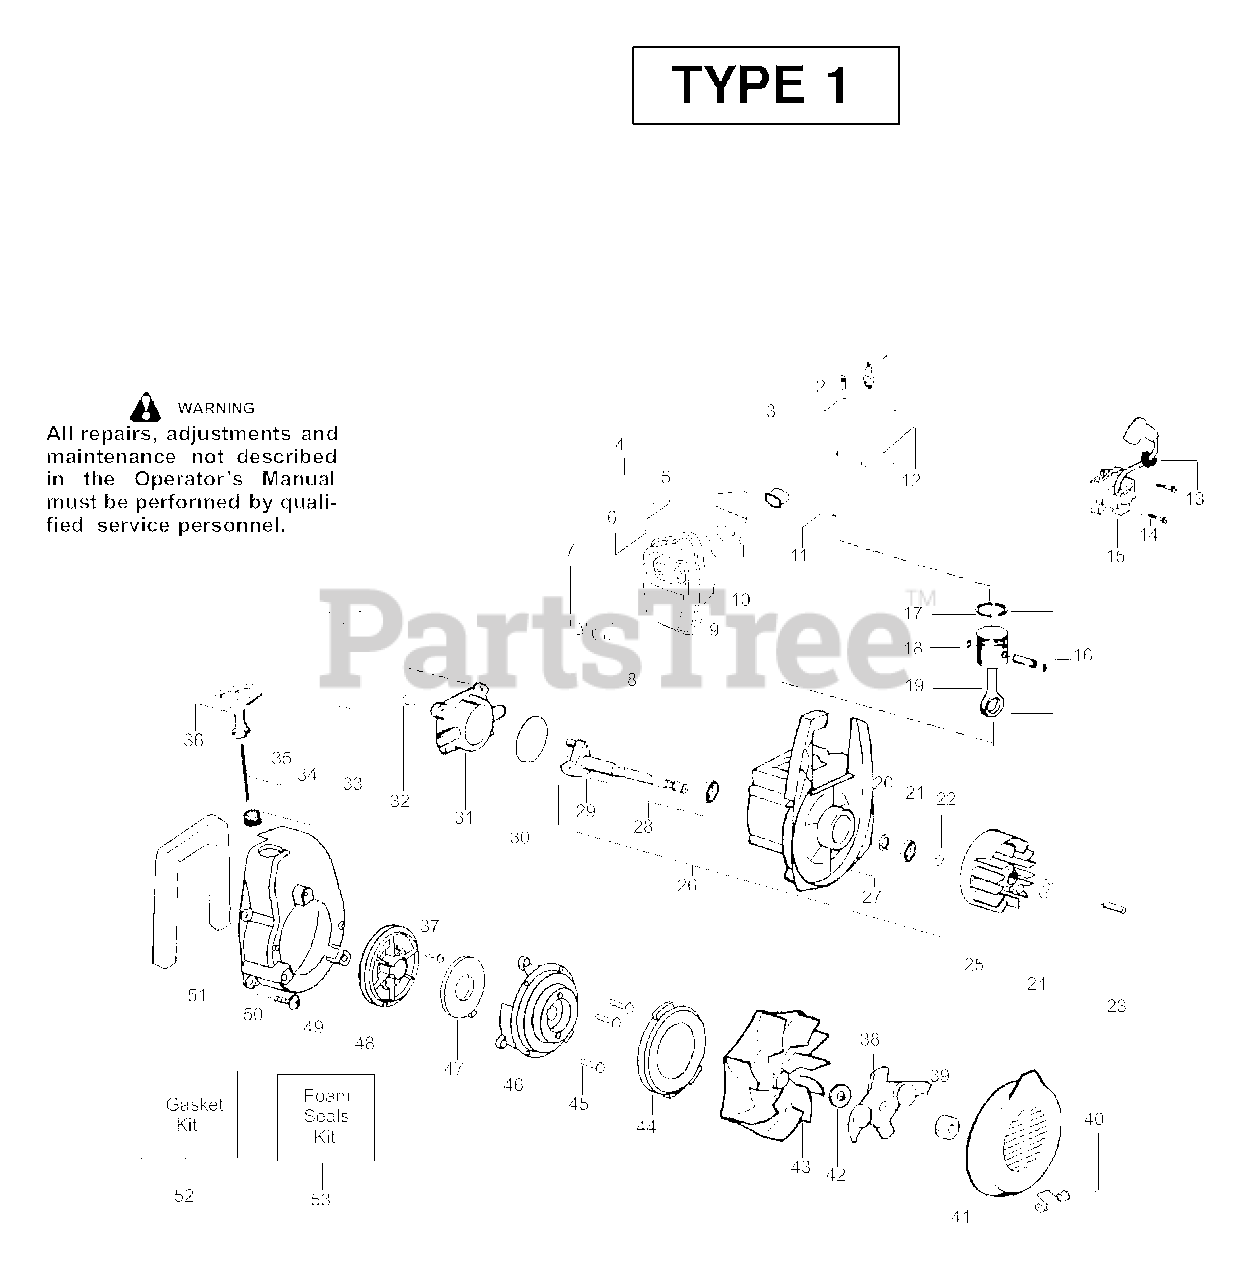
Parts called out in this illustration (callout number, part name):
1	Spark Plug (RCJ-6Y)
3	Insulator-Heat
5	Deflector-Muffler
6	Kit-Spark Screen
7	Bolt-Muffler-external
8	Screw-Muffler-Internal
9	Kit-Muffler
10	Gasket-Baffle (kit)
11	Gasket-Cylinder (kit)
12	Kit-Cylinder
13	Grommet-Ign. Module
14	Screw-Ignition Module
15	Ignition Module
16	Kit-Piston
17	Piston Ring
18	Retainer-Piston Pin
19	Assy-Connecting Rod
20	Seal-Crankcase
21	Bearing-Outer
22	Retainer Ring-C'chaft
23	Spacer-Flywheel
25	Assy-Flywheel
26	Assy-Crankcase/Crankshaft
27	Assy-Crankcase
28	Bearing-Inner
29	Assy-Crankshaft
30	O-ring-C/case (kit)
31	Cover-Crankcase
32	Screw
33	Foam-219mm (kit)
34	Eyelet-Flange
35	Kit-Rope
36	Handle-Starter
37	Screw-Rope
38	Assy-Mulch Blade
40	Spring-Return Cover
41	Inlet Door
42	Washer-Belleville
43	Assy-Impeller
44	Seal-Ring
46	Housing-Pulley
47	Spring-Starter
48	Kit-Starter Pulley
49	Fan Housing
50	Screw
51	Foam-365mm (kit)
52	Kit-Gasket
53	Kit-Foam Seals
